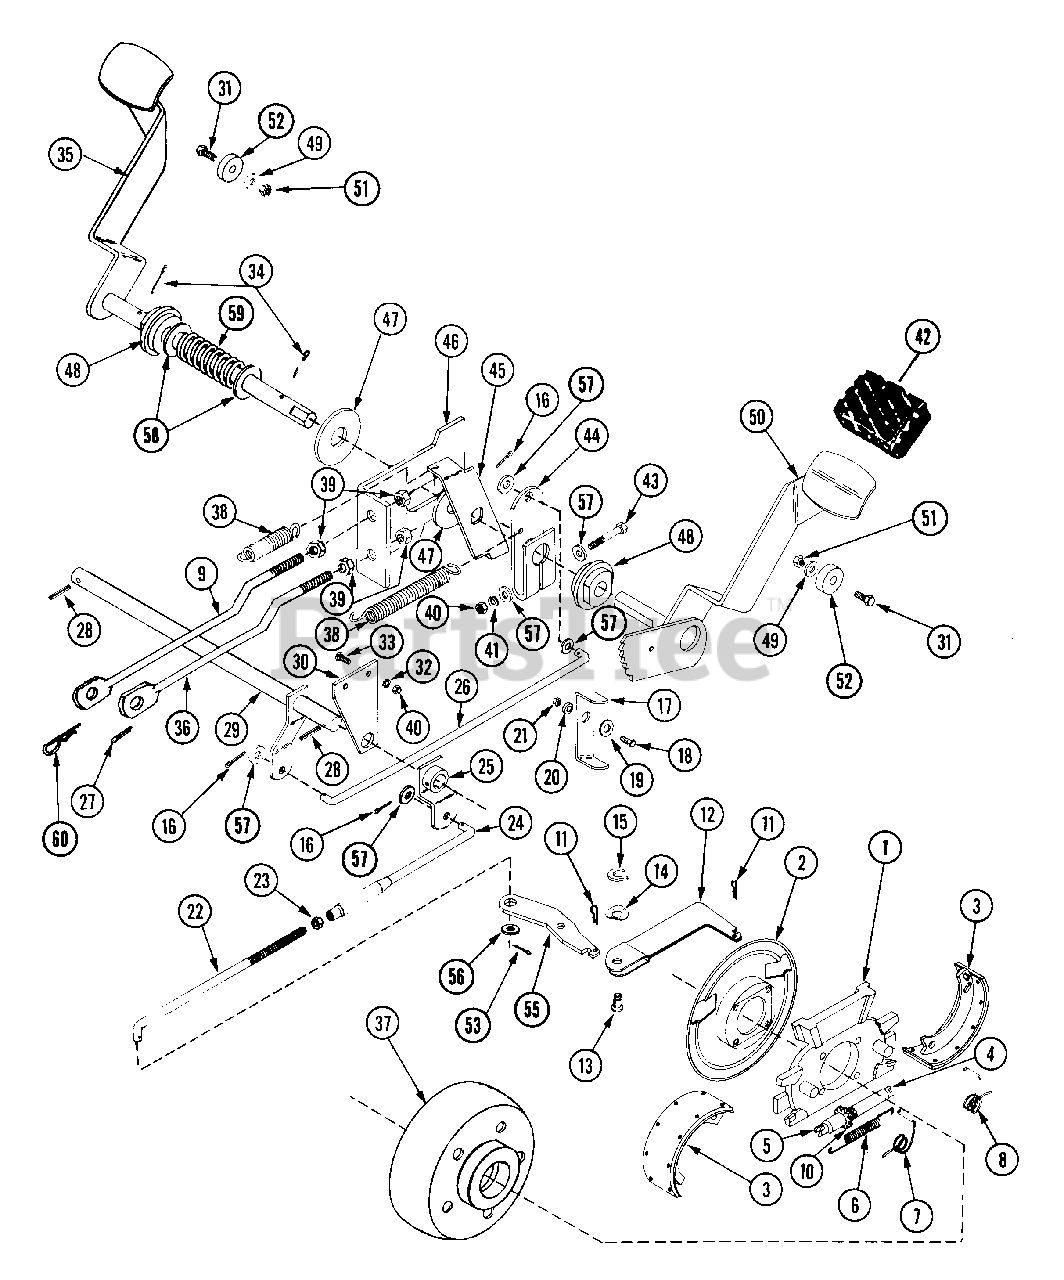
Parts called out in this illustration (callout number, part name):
1	TORQUE SPIDER
2	DUST SHIELD
3	PACKAGE - LINED SHOES
4	PIVOT NUT
5	SOCKET - ADJUSTING SCREW
6	SG-TENS ??X??X?? BENDIX
7	SG-TORS ??X??X?? BENDIX
8	SG-TORS BENDIX 3202132
9	SHIFT ROD
10	ADJUSTING SCREW
11	PIN-HAIR EXT .12X.75
12	STRUT ASSEMBLY
13	CLEVIS PIN
14	WSHR-FL-STL .380X.781X.013 PL
15	RETAINER
16	PIN-COTR .12X.75 PL
17	BRAKE LATCH
18	BLT-HEX .25-20X.75 PL GR2
19	WSHR-FL-STL.281X.62X.065 PL
20	SPACER BUSHING .37 X .26 X .14
21	NUT-LK-CTR .250-20 PL
22	LOWER SHIFT ROD
23	NUT-JAM .312-24 PL
24	BRAKE ROD
25	BRAKE ARM
26	BRAKE ROD
27	PIN-COTR .12X1.0 PL
28	PIN-GRV .250X1.25 TP A
29	BRAKE SHAFT
31	BLT-HEX .31-18X1.00 PL GR 2
32	WSHR-LK .375X.115 HVY PL
33	BLT-RDHDSQSHNK .38-16X1.00 PL
34	PIN-HAIR INT .09X1.88 PL
35	L.H. LEVER
36	NEUTRALIZER ROD
37	BRAKE DRUM
38	SG-TENS .090X.75X3.50 WLD 34
39	NUT .50-13 PL
40	NUT-HEX .375-16
41	WSHR-LK .375X.094 MED PL
42	PEDAL PAD
43	BLT-HEX .38-16X2.25 GR2
44	ARM-BRAKE
45	NEUTRALIZER ARM
46	NEUTRALIZER PLATE
47	WSHR-FL-STL .755X2.000X.125
48	BSHG-FLG .750X1.750X.875X2.125
49	WSHR-FL-STL .38X.875X.083 PL
50	R.H. LEVER
51	NUT-LK .312-18 GR A PL
52	SPACER .344X1.000X.375
53	PIN-COTR .09X.75 PL
54	WSHR-FL-STL .505X1.000X.062
55	PARKING BRAKE LEVER
56	WSHR-FL-STL .323X.625X.062 PL
57	WSHR-FL-STL.406X.812X.065PL
58	WSHR-FL-STL .755X1.375X.062 PL
59	SG-COMP .148X1.23X2.53 WLD87
60	PIN-HAIR INT .09X.188 PL
